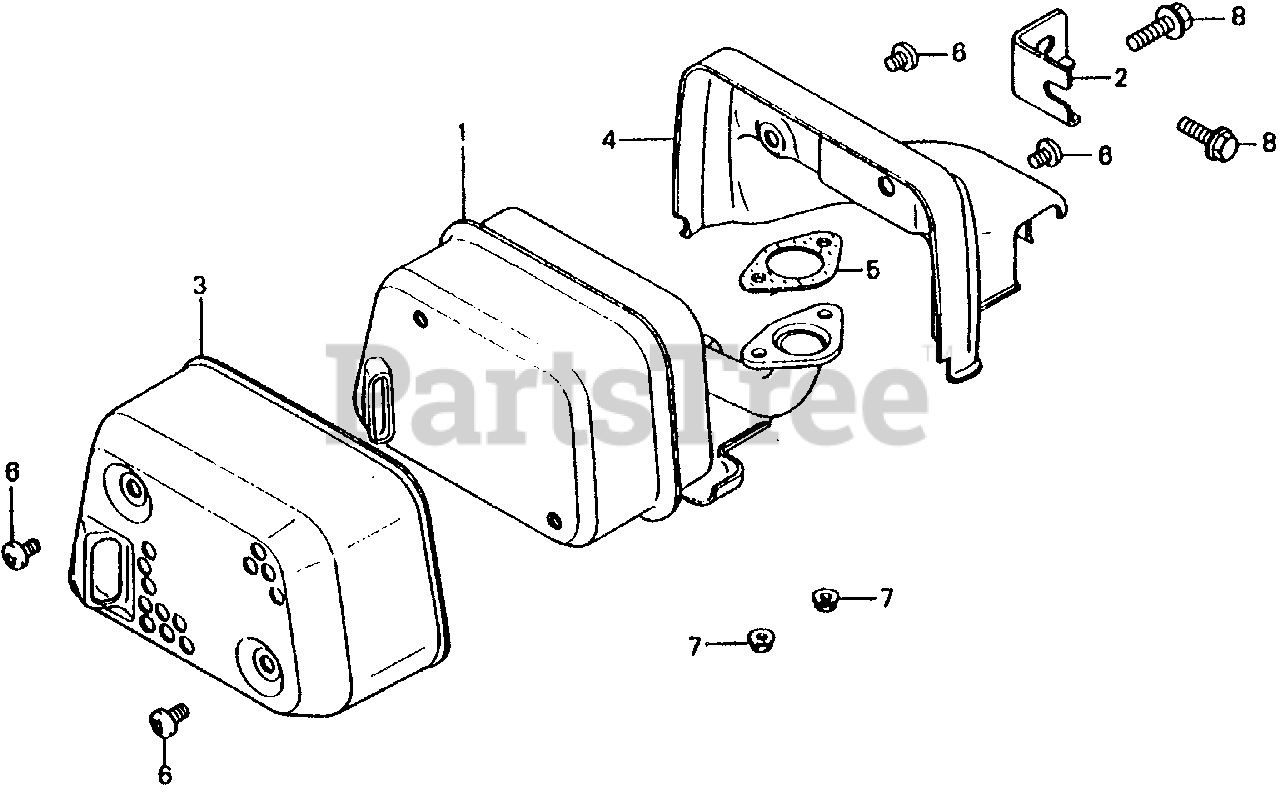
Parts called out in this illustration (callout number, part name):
2	STAY, MUFFLER
3	PROTECTOR, MUFFLER (NOT AVAILABLE)
4	COVER, EX. (UPPER)
5	GASKET, MUFFLER (NOT AVAILABLE)
6	SCREW, PAN (6X6)
7	NUT, FLANGE (6MM)
8	BOLT, FLANGE (6X12)
